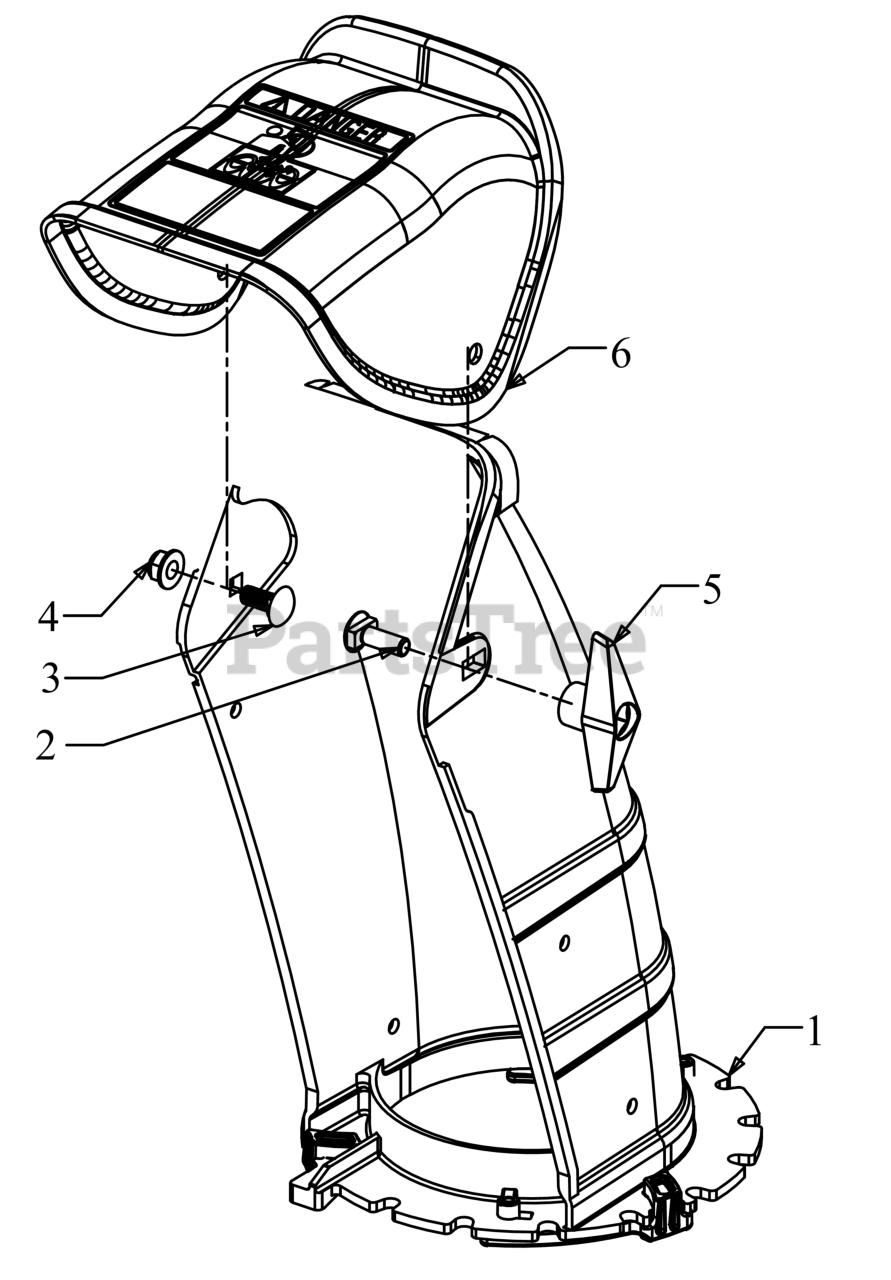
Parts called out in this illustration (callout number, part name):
1	2-WAY LOWER CHUTE ASSEMBLY
1	FLANGE KEEPER CHUTE
1	LOWER CHUTE 5"
2	CARRIAGE BOLT 5/16-18 x 1
3	CARRIAGE BOLT 5/16-18 x .75
4	FLANGE LOCK NUT 5/16-18
5	WING NUT KNOB
5	HEX NUT
5	STAR KNOB 5/16
6	UPPER CHUTE
